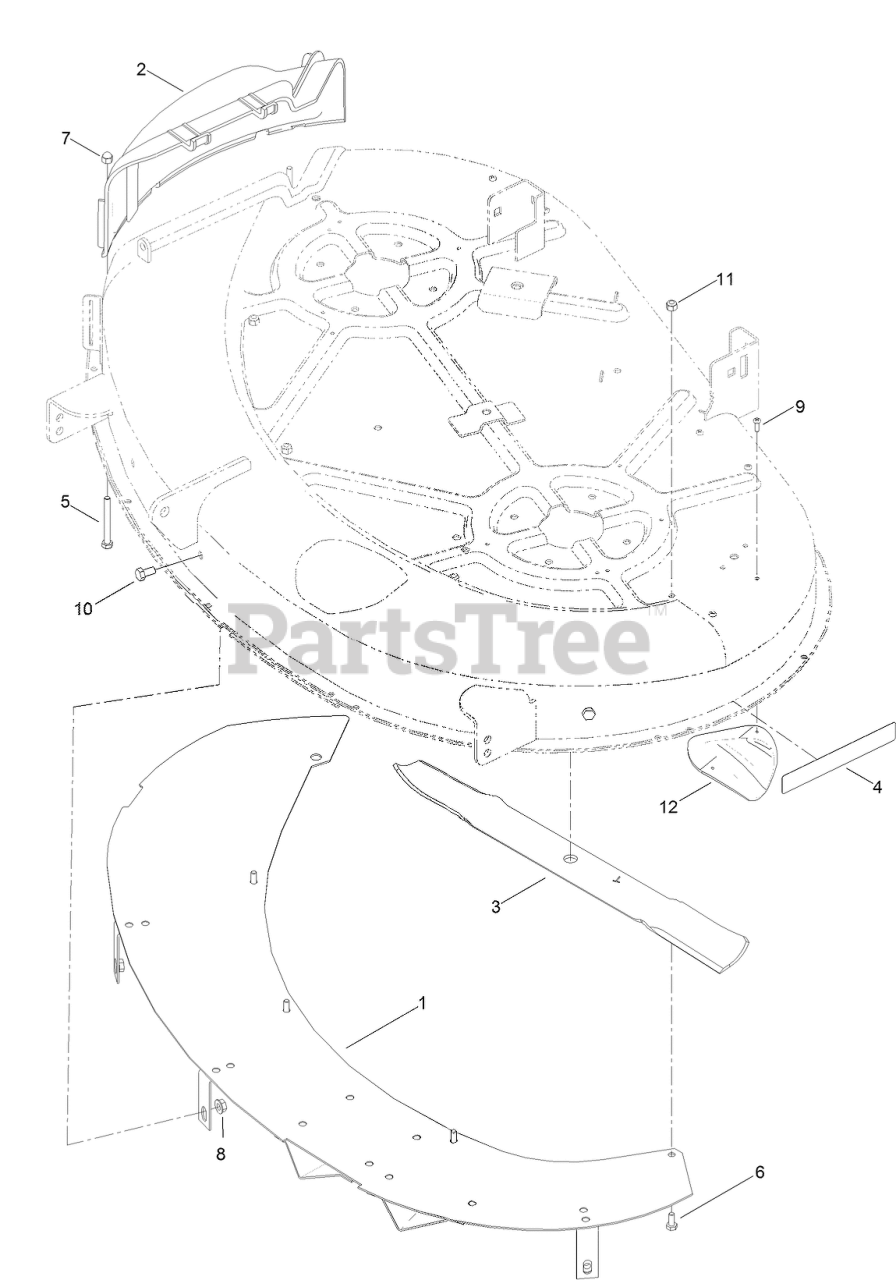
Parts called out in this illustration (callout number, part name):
1	BAFFLE UPPER ASM
2	COVER-DISCHARGE
4	DECAL-RECYCLER
5	SCREW-HH
6	SCREW-HH
7	NUT-CAP
8	NUT-HF
9	SCREW-PPH
10	SCREW-HH
11	NUT-LOCK, NI
12	PLATE-KICKER
